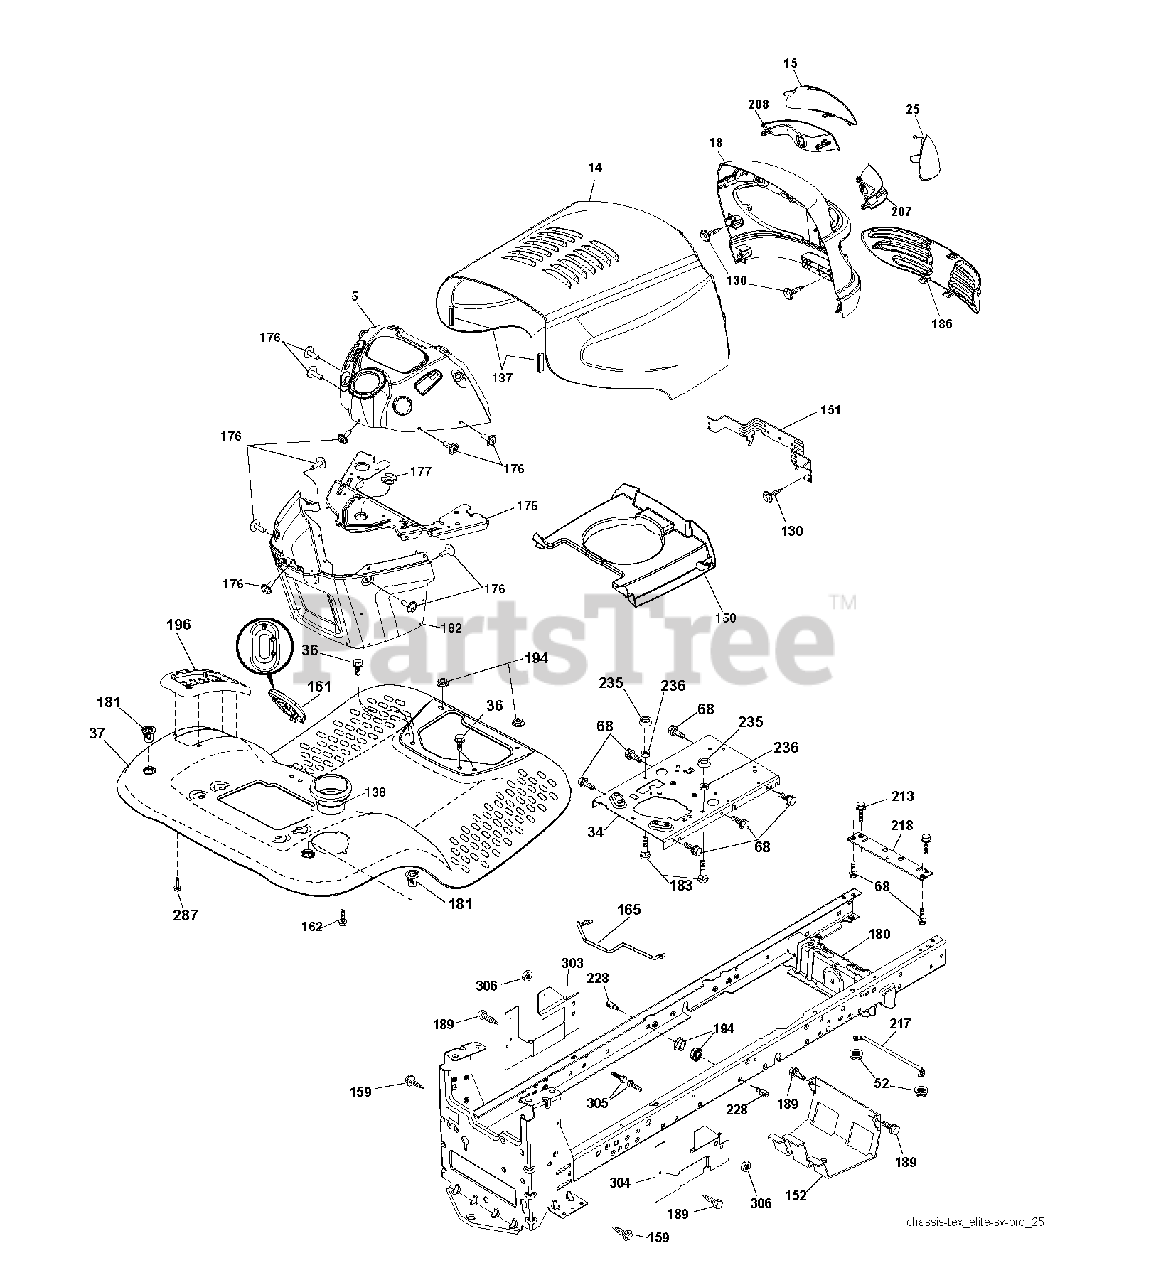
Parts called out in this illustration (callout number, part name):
14	BOLT.SHOULDER.SECTOR.P
34	PLATE.ENGINE.WELDED.CHASSIS
36	SCREW 3/8-16X3/4
52	LOCKNUT
130	SCREW.#10 X 0.750.BOS THREAD
137	BUMPER.HOOD.LARGE.1.75"
138	CUPHOLDER.TL.TEX.BLACK
151	BRACKET PIVOT
152	SHIELD BROWNING
159	SCREW, 3/8-16X3/4
161	RP WINDOW.FUEL.LT.TEX.GREY
162	SCREW.HI-LO.CONSOLE
165	SUPPORT.TANK.REAR.W/TE
175	CROSSMEMBER.LT
176	SCREW.#10-24X5/8.RN.QU
177	BUSHING STEERING
180	CHASSIS
181	FEND/FTRST.PCH.CPH.NFW
182	DASH.LOWER.LT.CCS
183	BOLT.5/16-18X1-1/4 FULL THD
189	SCREW
194	NUT LOCK HEX FLANGE 5/16-18
196	CONSOLE.ASM.DECKLFT.BL/RBT.TLT
207	BEZEL GRILL RH
208	BEZEL GRILL LH
213	BOLT
217	ROD.PIVOT.HOOD
218	X-PIECE.HOOD.STOP.NON/
228	STUD.FASTNER.W/ANTI-ROTATE
235	SPACER FENDER
236	NUT.CENTERLOCK.5/16-
306	NUT LOCK FLG 3/8-16 UNC
